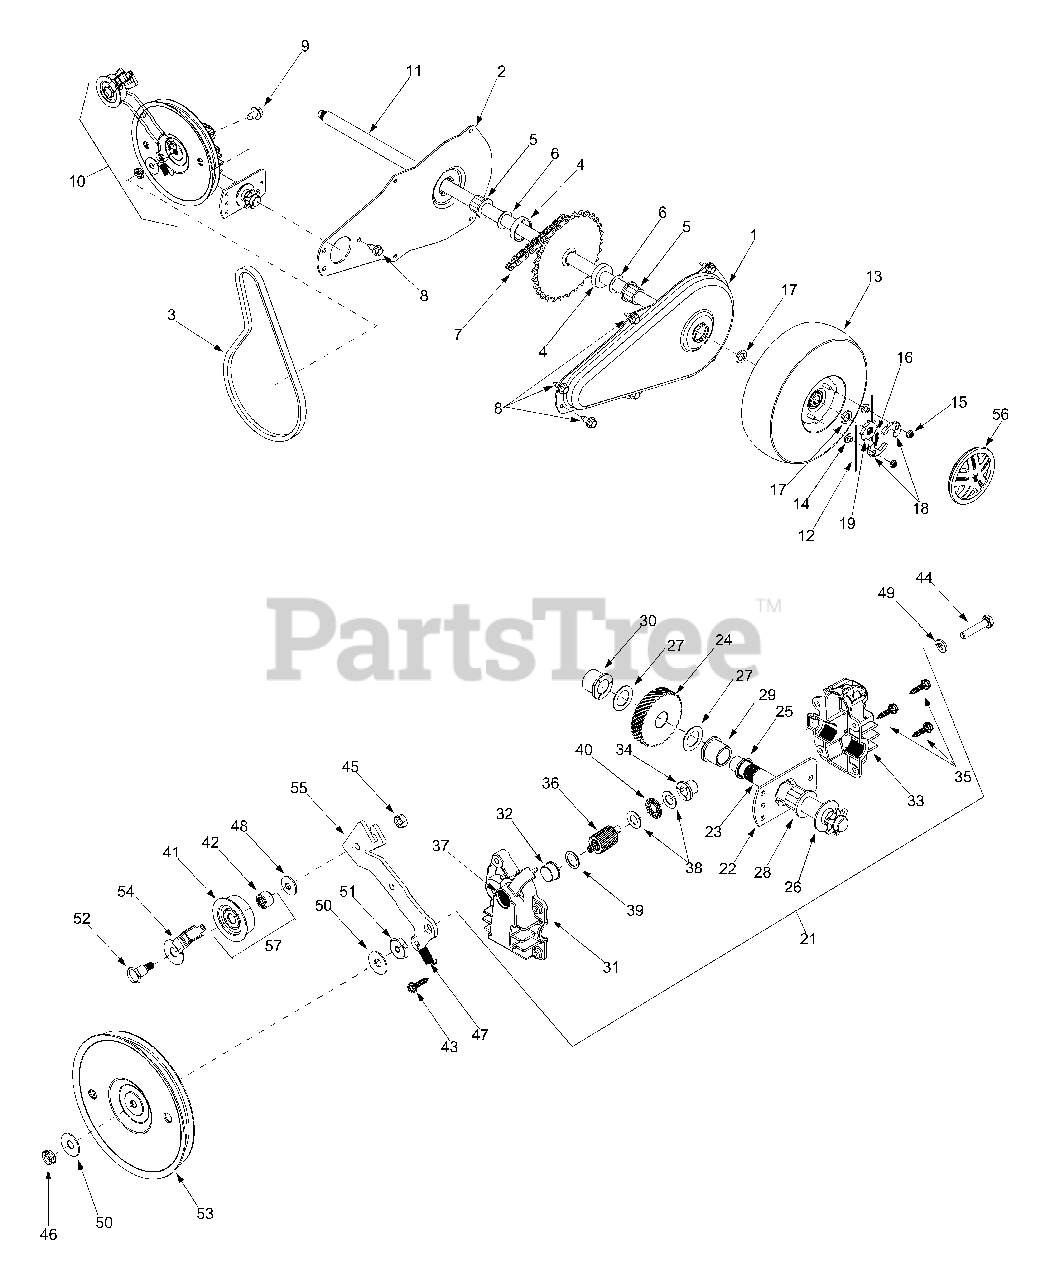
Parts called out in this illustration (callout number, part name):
3	V-Belt
4	Spacer
5	Hex Flange Bearing
6	Flat Washer
7	Chain
8	Self Tapp. Screw 1/4-14 x.625
9	Hex Washer Screw 5/16
10	Chipper Shredder Trans. Assembly
11	Axle Shaft Assembly
12	Plastic Spring Ratchet
13	Wheel Complete 10 x 4 x 4
14	Hex Nut 1/4-20
15	Hex Flanged Lock Nut 1/4-20
16	Cotter Pin
17	Flat Washer 5/8 ID x 1.0 OD
18	Pawl LH.345 ID
19	Wheel Ratchet 1.62 OD x.5 serr
21	6T Shredder Transmission Assy.
23	6T Sprocket Output Shaft
24	Helical 34T Gear
25	Oil Seal
26	Flat Washer.64 ID x 1.24 OD
27	Flat Washer 5/8 x 1.0
28	Hex Flange Bearing.631 ID
29	Flange Bearing.629 ID
30	Flange Bearing.566 ID
31	Lower Housing
32	Flange Bearing.503 ID
33	Upper Housing
34	Flange Bearing.378 ID
35	Hex Washer Screw #10-16 x.75
36	Pinion Shaft 10T
37	Oil Seal
38	Thrust Washer.382 ID x.684 OD
39	Flat Washer.504 ID x.70 OD
40	Thrust Bearing.375 ID x.812 OD
41	Idler Pulley
42	Needle Bearing.375 ID x.375 OD
43	Hex Screw #10-16 x.75
44	Hex Cap Screw 1/4-20 x 1.25
45	Hex Nut 1/4-28
46	Hex Jam Nut 5/16-24 LH Thd
47	Extension Spring 1.12 Lg
48	Bell Washer.265 ID x.75 OD
49	Lock Washer 1/4
50	Bell Washer.325 ID x.930 OD
51	Shoulder Spacer.375 ID x.165 OD
52	Shoulder Bolt 1/4-28 x.375
53	Flat Pulley 5.06 Dia
54	Belt Keeper
55	Idler Bracket Assembly
56	Hub Cap
57	Idler Pulley Assembly w/Bearing
